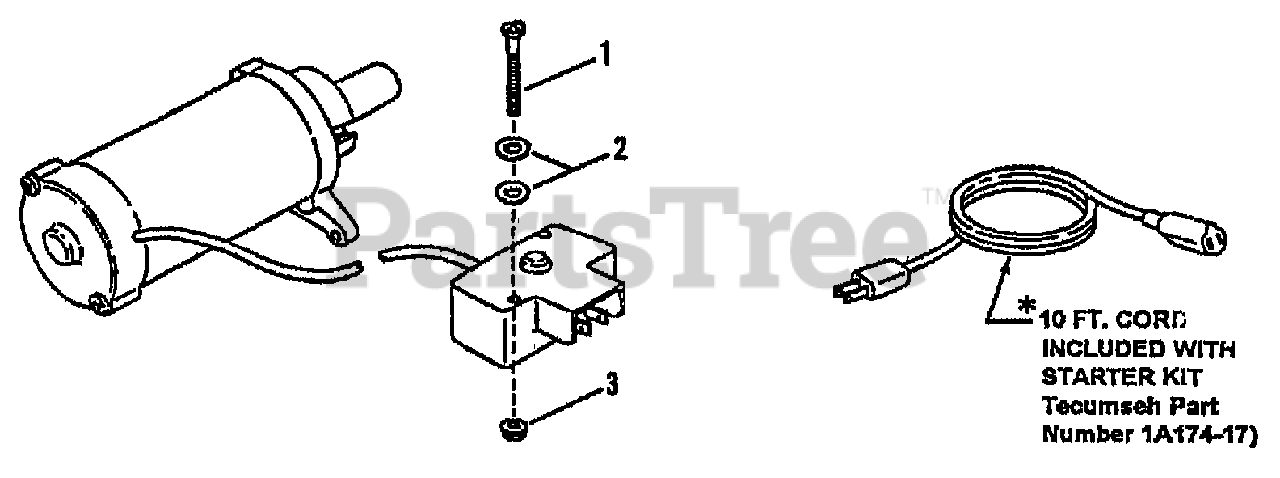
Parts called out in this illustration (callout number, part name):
1	SHOE-FLITE
2	SHOE-CENTER FLITE
3	SCR-MACH 1/4-20X.5
